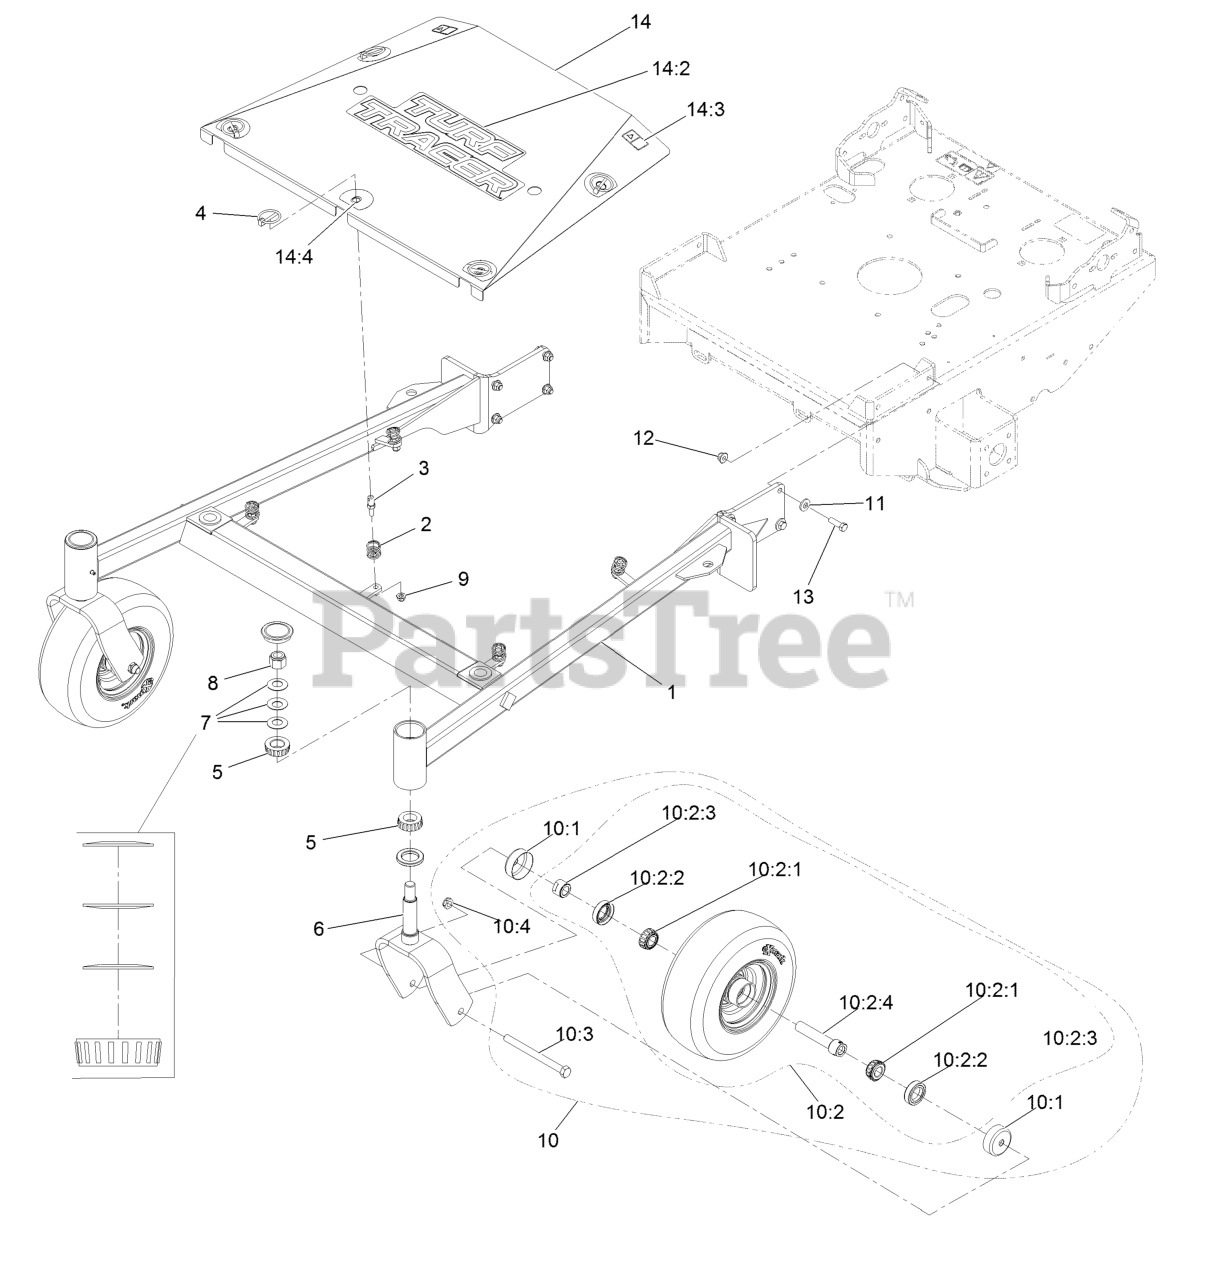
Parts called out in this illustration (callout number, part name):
1	ASM, Front Frame W/ Bearings, 52
3	Pin-Spring
4	Pin-Lynch
5	Cone-Bearing Tapered Roller
6	Wld, Caster Fork
7	Washer-Spring Disc
8	Nut-Nyloc 3/4-10
9	Nut-Nyloc 5/16-18 Flg
10	Asm, Wheel And Bearings
10:1	Guard-Seal
10:2	Wheel And Bearing ASM
10:2:1	Bearing-Cone Tapered Roller
10:2:2	Seal-Double Lip
10:2:3	Spacer-Nut
10:2:4	Caster Axle ASM
10:3	Screw-HH 1/2-13 X 6
10:4	Nut-Nyloc 1/2-13 Thin
11	Washer-Spring Disc 3/8
12	Nut-Nyloc 3/8-16 Flg
13	Screw-HH 3/8-16 X 1 1/4
14	ASM, Center Shield W/Decals, 52
14:2	Decal-Turf Tracer
14:3	Decal-Warning
14:4	Decal-Scratch Cover
